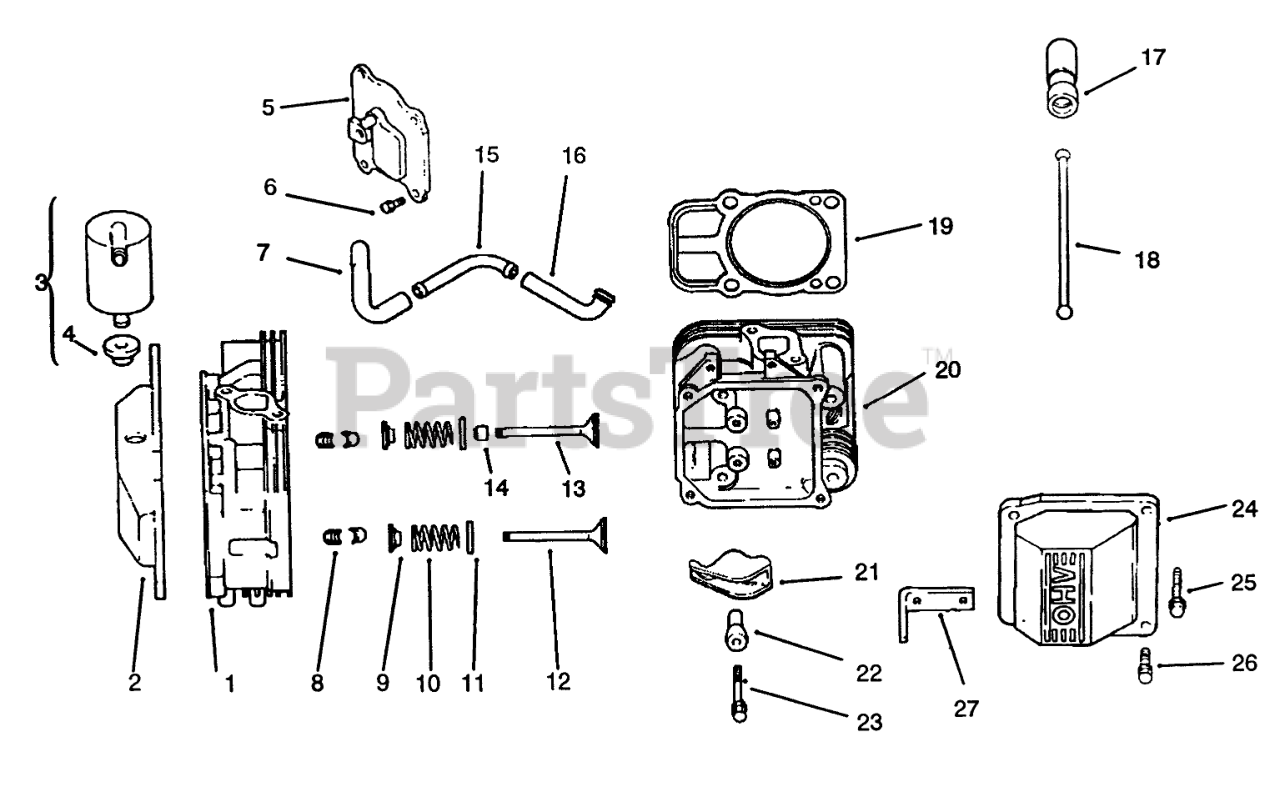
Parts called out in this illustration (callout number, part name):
1	Head ASM-#1 Cylinder (Only On: 72103, 72083)
2	Cover-Rocker (Only On: 72103, 72083)
3	Kit-Breather INC 4 (Only On: 72103, 72083)
4	Grommet-Rubber (Only On: 72103, 72083)
5	Cover-Breather (Only On: 72103, 72083)
6	Screw M6x1.0x20 (Only On: 72103, 72083)
7	Hose-Breather (Only On: 72103, 72083)
8	Kit-Retainer (Only On: 72103, 72083)
9	Cap-Valve spring (Only On: 72103, 72083)
10	Spring-Valve (Only On: 72103, 72083)
11	Retainer-Spring (Only On: 72103, 72083)
12	Valve-Exhaust (Only On: 72103, 72083)
13	Valve-Intake (Only On: 72103, 72083)
14	Seal-Valve Stem (Only On: 72103, 72083)
15	Fitting (Only On: 72103, 72083)
16	Hose-Breather (Only On: 72103, 72083)
17	Lifter-Valve (Only On: 72103,72083)
18	Rod-Push (Only On: 72103,72083)
19	Gasket-Cylinder Head (Only On: 72103, 72083)
20	Head ASM-#2 Cylinder (Only On: 72103, 72083)
21	Arm-Rocker (Only On: 72103,72083)
22	Ball-Rocker Pivot (Only On: 72103, 72083)
23	Screw M6x1.0x34 (Only On: 72103, 72083)
24	Cover-Rocker (Only On: 72103,72083)
25	Screw M 10x1.5x91 (Only On: 72103, 72083)
26	Screw M6x1.0x30 (Only On: 72103, 72083)
27	Strap-Lifting (Only On: 72103, 72083)
